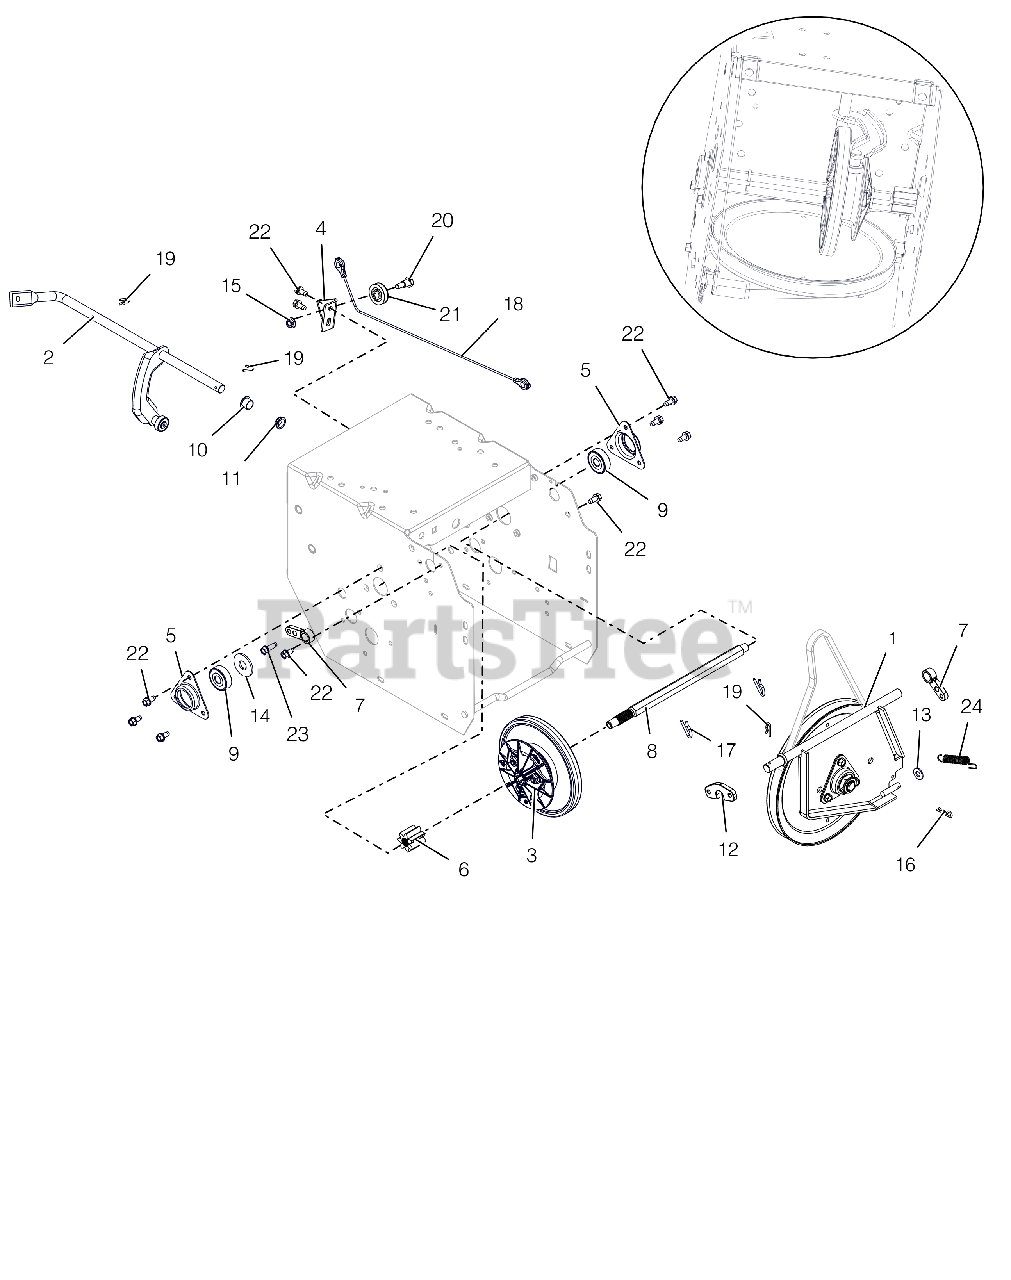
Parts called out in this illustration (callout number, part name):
1	PLATE, SWING - ASSEMBLY
2	ARM, SHIFT-SMALL DASH (WLDMT)
3	DISC, FRICTION DRIVE-ASSEMBLY
4	BRACKET, CABLE PULLEY
5	FLANGE, BEARING
6	GEAR, PINION, 7 TOOTH W/SPLINE
7	SUPPORT BUSHING, SWING GATE
8	SHAFT, HEX W/SPLINE
9	BRG-BALL .437X1.375X.437
10	BUSHING, POLYLINER-.50 SPLIT
11	BUSHING, POLYLINER-.50 SNAPIN
12	SPACER, SWING GATE
13	@WSHR-FL-STL.344X.688X.065YWZC
14	@WSHR-FL-STL.563X1.38X.109YWZC
15	@NUT-LK-CTR-FLG .25-20 YWZC
16	PIN-HAIR INT .08X.18X1.18 YWZC
17	PIN, SPRING CLIP
18	CABLE, LOWER TRACTION (CMPCT)
19	CLIP, SPRING
20	BOLT, SHLDR-.375X.375X.25-20
21	PULLEY, CABLE
22	SCR-TAP .25-20X.50 HWH TR YWZ
23	SCR-TAP-PM .25-20X.75 TR YWZ
24	SPRING, EXT. .043X.438X1.64
